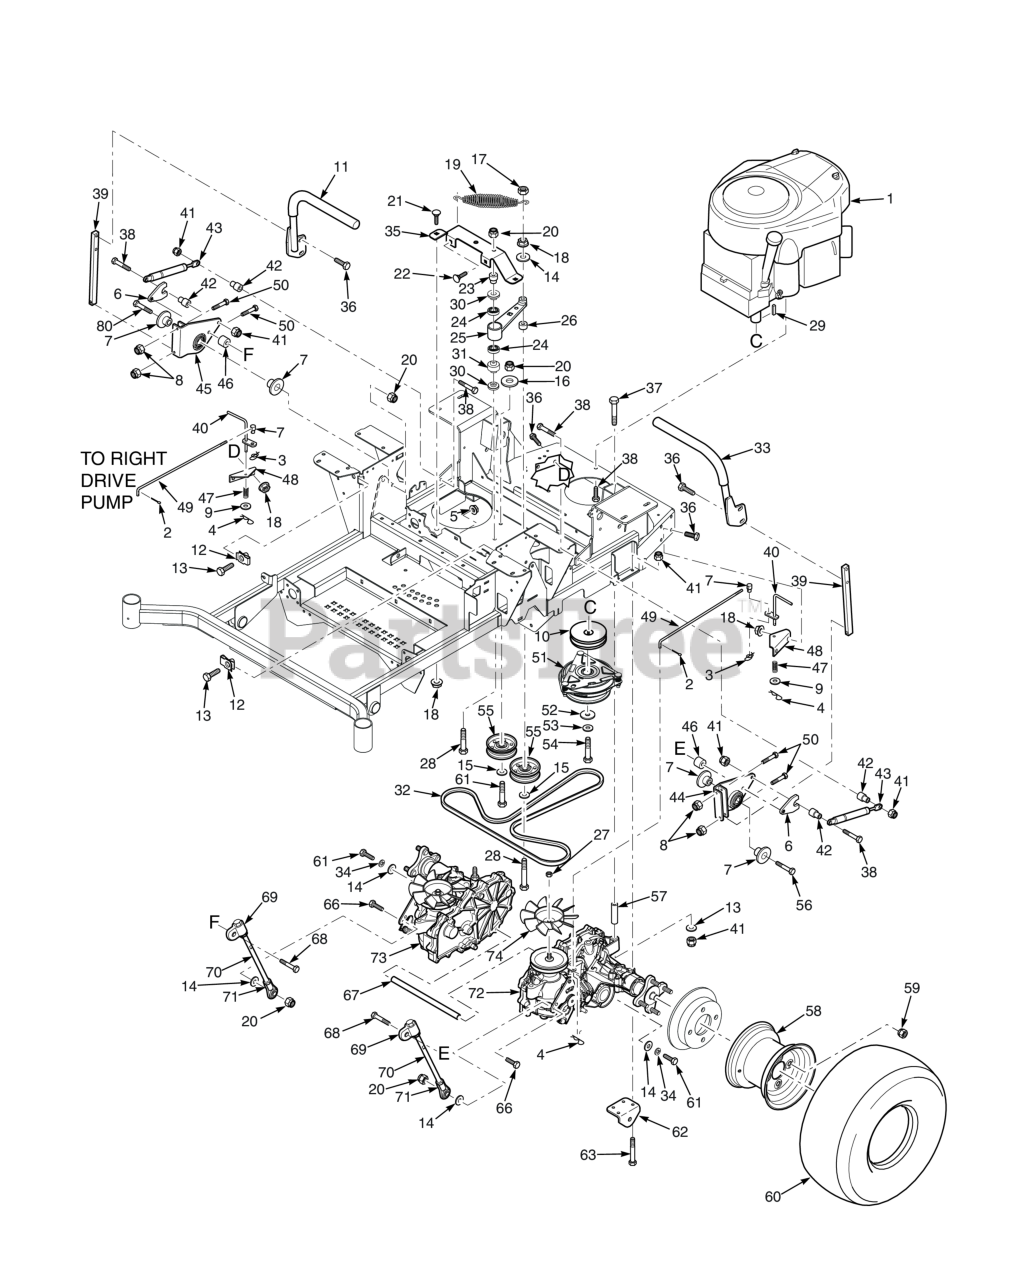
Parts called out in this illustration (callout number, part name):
1	Engine, Kawasaki - 22FX
2	COTTER PIN, 3/32 X 1"
3	Pin, Rue Cotter 3/8" Diameter
4	HAIR PIN, .08 DIAMETER X 1-3/16"
5	Nut, Serrated Flange 5/16-18 (Right Front Engine Mounting, Briggs and Kohler Only)
6	Nut, Control Linkage
7	Spacer, Linkage
8	HEX, NUT, ELASTIC STOP LOCK, 1/4-20
9	Flatwasher, 1/4" (.312 x .750 x .065")
10	Pulley, 5" OD - 1.125 Bore (SPZ61H)
11	Handle Bar Assembly RH, w/Grip
12	U-Nut, 3/8-16 (short)
13	Bolt, Hex Head 3/8-16 x 1-1/4" Special Lock
14	Flatwasher, 3/8" Special (.391 x .938 x .105)
15	Flatwasher, 3/8 (.391 x .938 x .105 HD) Grade 8
16	Flatwasher, 3/8-.406 x 1-1-1/2 x 7 Gauge
17	Bolt, Hex Head 3/8-16 x 1" Ser. Flg.
18	NUT, 3/8-16 SERRATED FLANGE HEX HEAD
19	Spring, Transmission Idler
20	HEX NUT, ELASTIC STOP LOCK, 3/8-16
21	Bolt, Carriage 3/8-16 x 3/4"
22	Bolt, 5/16-18 x .75 RHSN Carriage
23	Shaft Pivot, Idler Arm
24	BEARINGS, BALL, NEUTRAL RETURN
25	Trans. Idler Arm Assy. (Includes 24, 79)
26	Spacer, Idler Pulley - SFZ61
27	Fan Nut (order through Hydro-Gear)
28	Capscrew, Hex Head 3/8-16 x 3.25"
29	Key, 1/4" x 1/4" x 2-3/4" Pulley Mtg.
30	Spacer, Controls
31	Spacer, Bearing
32	Belt, Transmission Drive - SFZ61
33	Handle Bar Assembly LH, w/Grip
34	Lockwasher, 3/8" Spring, Kawasaki FX / FT & FT-EFI / B&S 32BV
35	Support, Idler Arm
36	Capscrew, 3/8-16 x 1.0" Serrated Flange Hex Hd
37	HEX HEAD BOLT, 5/16-18 X 5"
38	Bolt, Hex Head 5/16-18 x 1-1/2" (Right Front Engine Mounting, Briggs and Kohler Only)
39	Bar, Control Lever
40	Dump Valve Lever
41	HEX NUT, ELASTIC STOP LOCK, 5/16-18
42	Spacer, Pump Dampener
43	Gas Damper
44	Control Link, LH
45	Control Link, RH
46	Spacer, Idler Pulley - SFZ52
47	Spring, Dump Valve Link
48	Bracket, Dump Mounting
49	Rod, Brake Adjustment
50	Bolt, Hex Head, 1/4-20 x 1-1/2"
51	Electric Clutch Assembly - SFZ52 & SFZ61
52	Flatwasher, 7/16-.469 x 1.75 x .25 (48, 52)
53	Lockwasher, 7/16� Spring
54	Bolt, Hex Head 7/16-20 x 1-1/2" Patch Kawasaki 22FX & 23FX
55	Pulley, 3-1/2" Dia.
56	Capscrew, Hex Head 3/8-16 x 2.0"
57	Spacer, Axle - SFZ61
58	Rim w/Valve Stem, (Scag Gold) - SPZ61H
59	Wheel Nut, 1/2-20 x 13/16
60	Wheel Assembly, 24 x 12-12 (SPZ61)
61	Capscrew, Hex Head 3/8-16 x 2-1/2"
62	Bracket, Push Arm Link
63	Bolt, Hex Head 5/16-18 x 3.00"
64	Clip, Brake Lever (order through Hydro-Gear)
65	Lever, Brake (order through Hydro-Gear)
66	Bolt, Hex Head 3/8-16 x 1-1/2" B&S 32BV
67	Spacer, Axles
68	Capscrew, Hex Head 3/8-16 x 2.0"
69	Rod End, Adjustable 3/8-24
70	Linkage, Pump - SFZ61
71	Stake, Rod End Assembly
72	Transaxle Assy., LH (ZY-GCEE-SL7F-11TX) SPZ61H
73	Transaxle Assy., RH (ZY-KCEE-SL7G-11TX) SPZ61H
74	Fan (order through Hydro-Gear)
